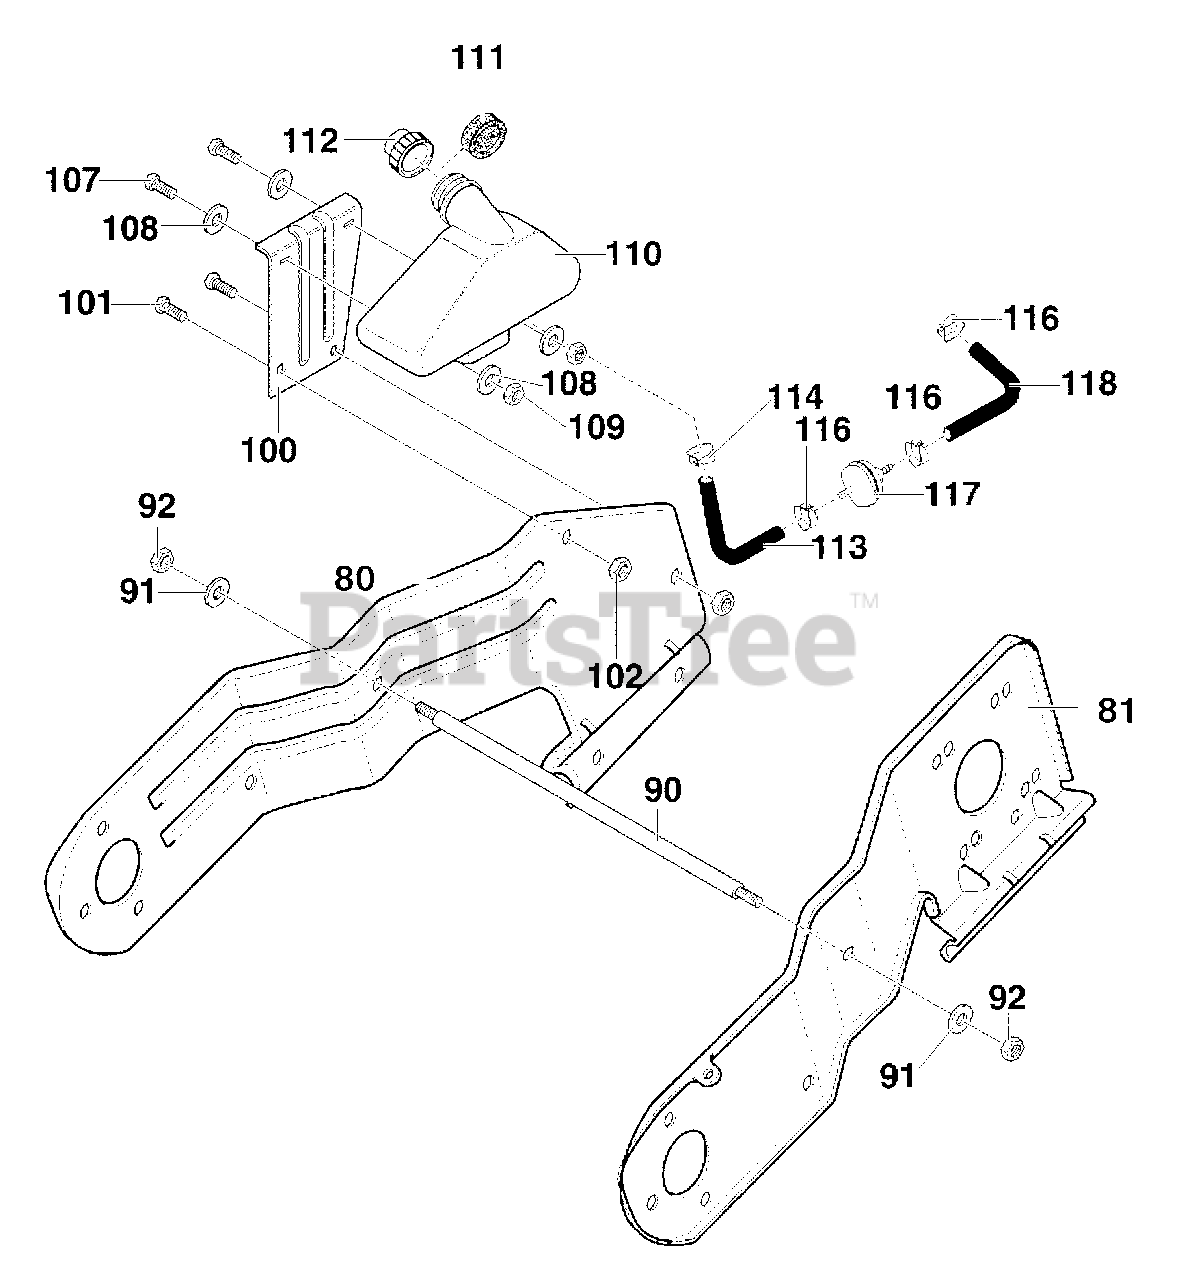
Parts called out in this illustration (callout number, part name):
80	FRAME, SIDE SUPT STEEL RH
81	FRAME, SIDE SUPT STEEL LH
90	ROD, SUPPORT
91	WASHER
92	NUT, 3/8-16 HEX
100	BRACKET, GAS TANK
101	SCREW, 1/4-20X.75
102	NUT, 1/4-20 HEX
107	SCREW, 1/4-20X.75
108	WASHER, FLAT
109	NUT, 1/420 HEX
110	TANK, FUEL
111	RING, FOAM FUEL TANK
112	CAP, GAS
113	TUBING 8 IN.
114	CLAMP, HOSE SCREW
116	CLAMP, HOSE
117	FILTER IN LINE
118	TUBING, 6 IN.
